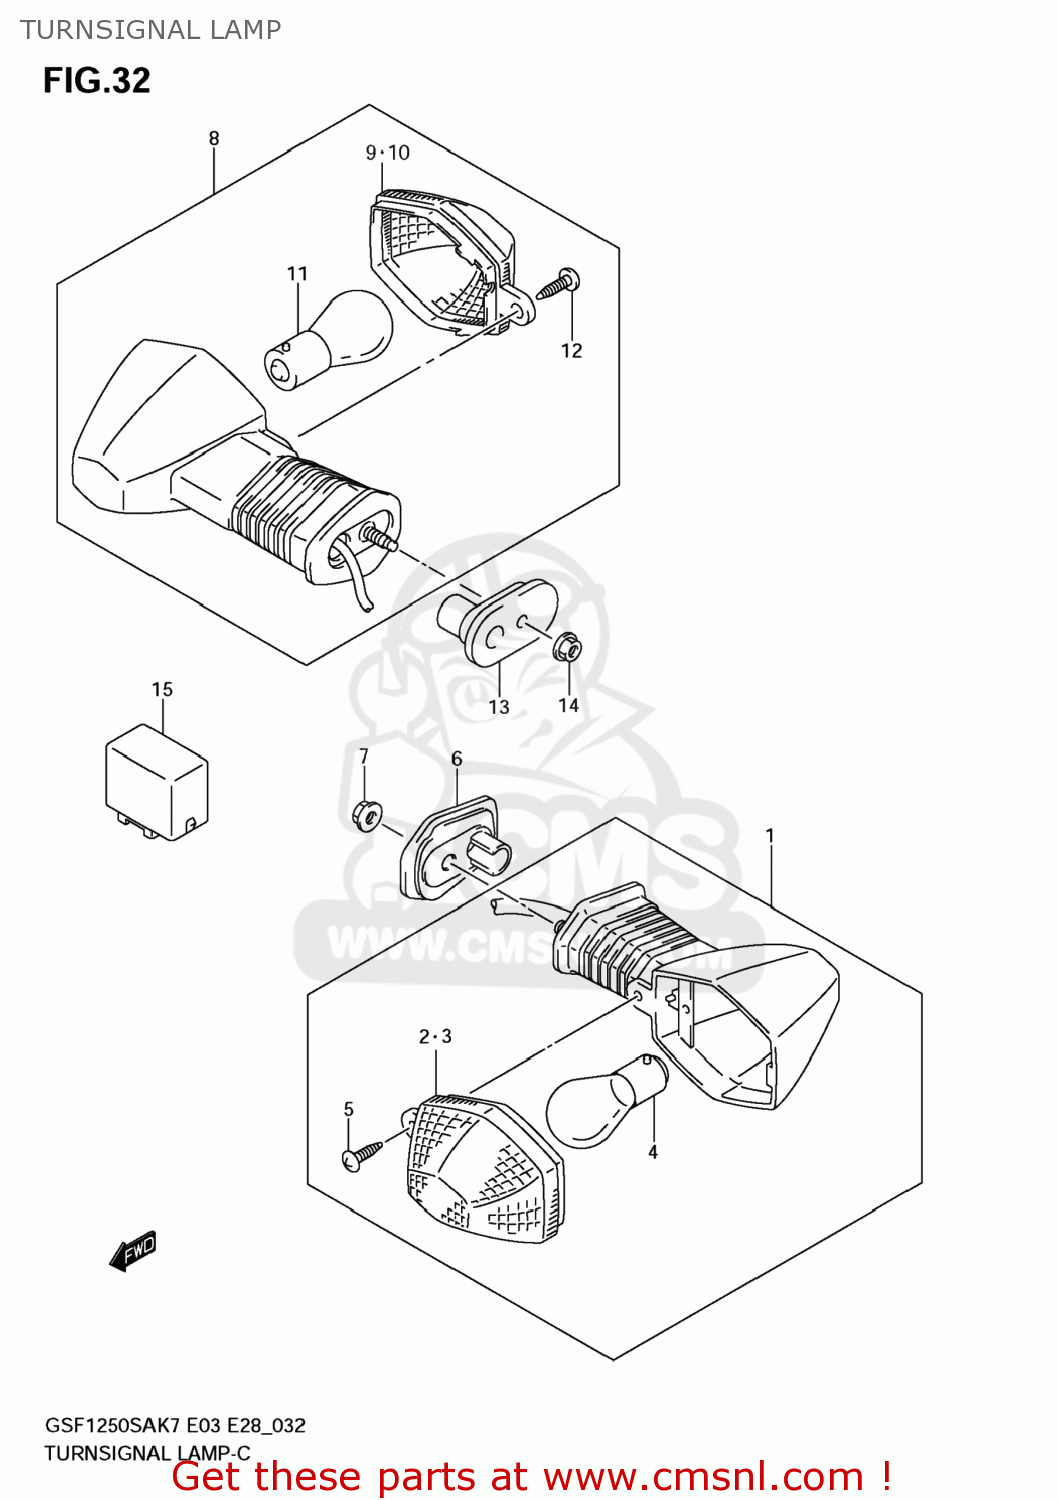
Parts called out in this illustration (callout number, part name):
1	LAMP ASSY,FR TURN SIGNAL,R
2	LENS
3	LENS
4	BULB(12V21W,AMBER)
5	SCREW
6	PLATE,FR TURNSIGNAL
7	NUT
8	LAMP ASSY,RR TURNSIGNAL,R
9	LENS
10	LENS
11	BULB(12V21W,AMBER)
12	SCREW
13	PLATE,TURNSIGNAL LAMP
14	NUT
15	RELAY ASSY,TURNSIGNAL LAMP
